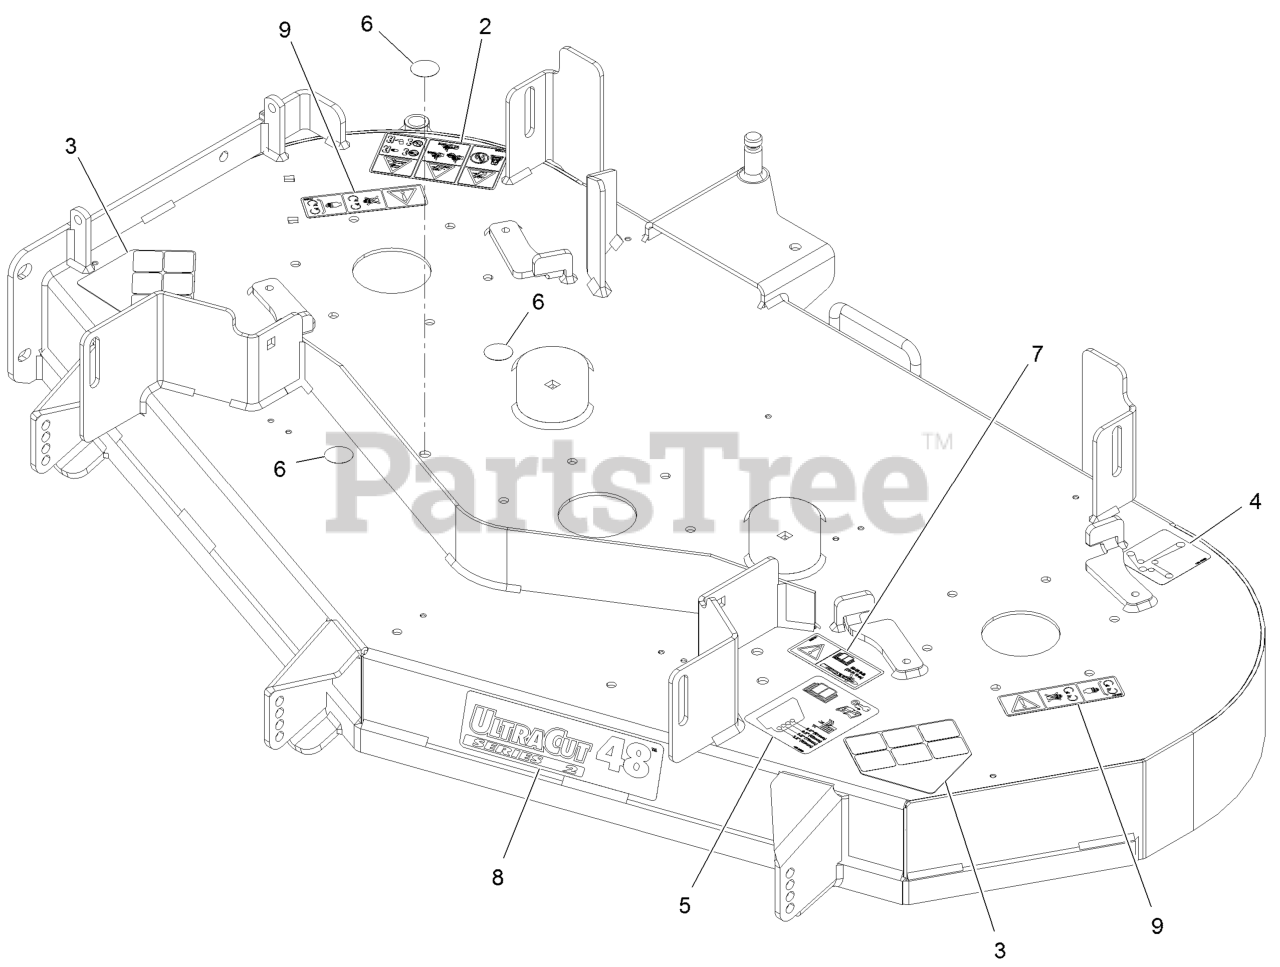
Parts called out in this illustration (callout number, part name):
2	DECAL-DANGER
3	DECAL-DANGER
4	DECAL-ROUTING, BELT
5	DECAL-ROLLER, ANTI-SCALP
6	DECAL-HOLE COVER
7	DECAL-BOLT TORQUE
8	DECAL-ULTRACUT 48 SERIES
9	DECAL-COVER, MISSING
